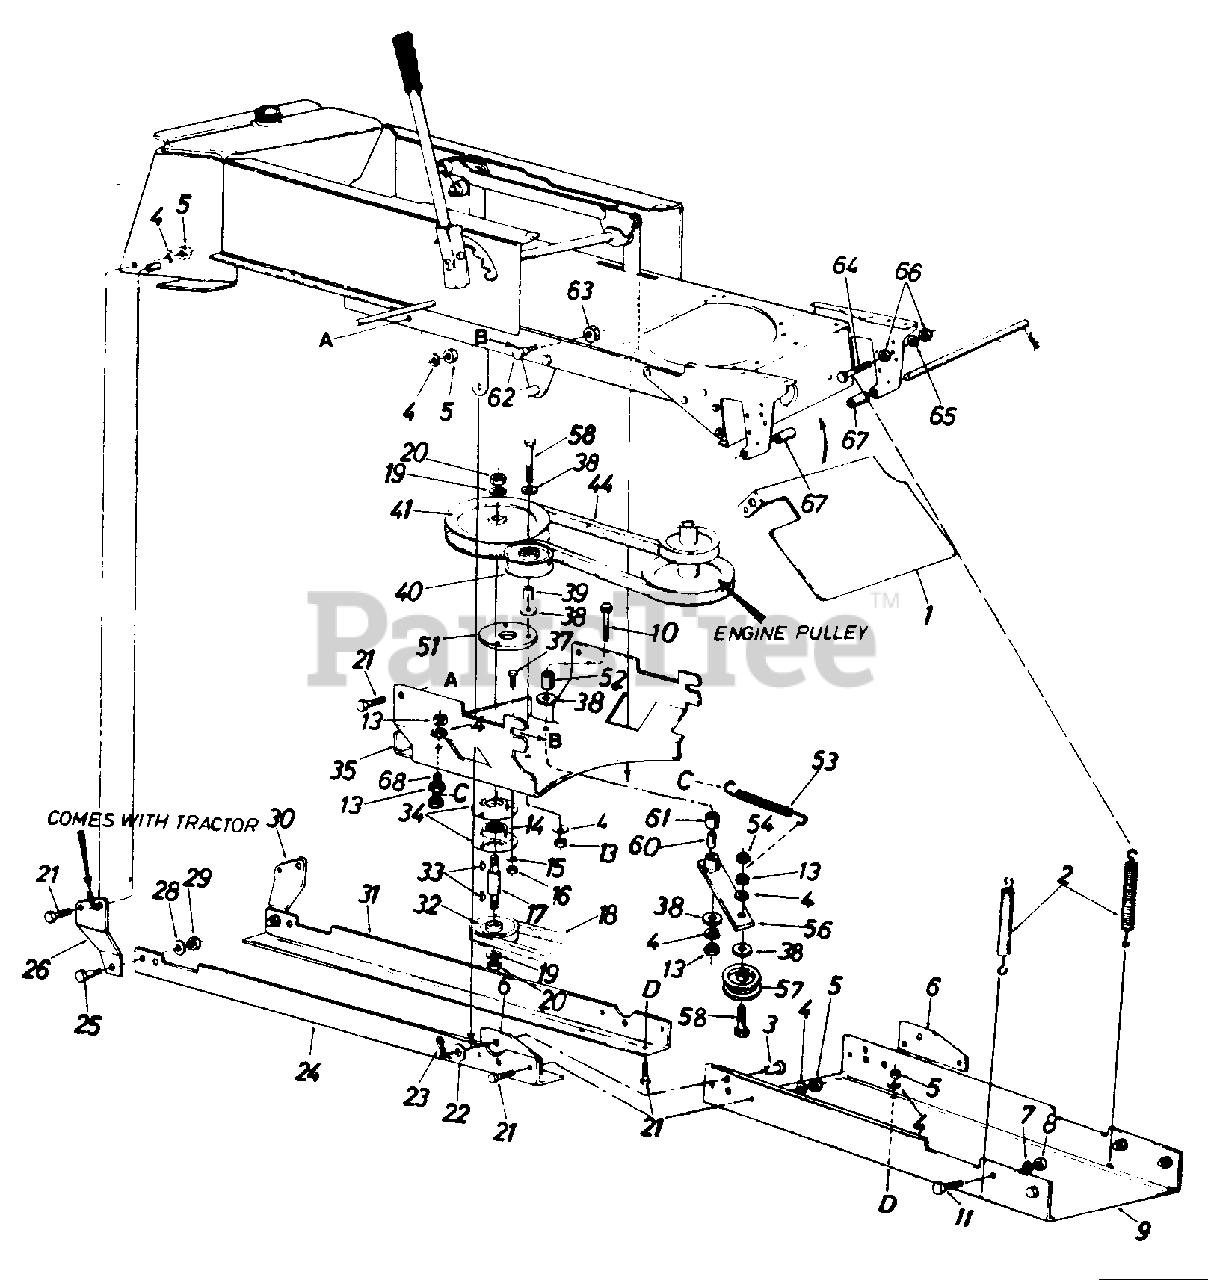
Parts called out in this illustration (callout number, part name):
3	Clevis Pin
4	L.-Wash. 3/8" I.D.
5	Hex L.-Nut 3/8-24 Thd.
6	Attaching Plate
7	L.-Wash. 1/2" I.D.
8	Hex L.-Nut 1/2-20 Thd.
11	Hex Bolt 1/2-20 x 1.25" Lg.
13	Hex Jam Nut 3/8-16 Thd.
14	Ball Bearin
15	L.-Wash. 5/16" I.D.
16	Hex Nut 5/16-18 Thd.
17	Spindle
18	"V"-8elt
19	L-Wash. 5/8" I.D.
20	Hex Jam Nut 5/8-11 Thd.
21	Hex Bolt 3/8-24 x 1.00" Lg.
22	Flat Washer
23	Internal Cotter Pin
29	Hex Nut 7/16-14 Thd.
33	#6 Hi-Pro Key 3/16 x 5/8" Dia.
34	Bearing Housing N
35	Supporting Bracket N
37	Hex Sems Bolt 5/16-18 x l"
38	Fl.-Wash. .38" I.D. x l" O.D.
39	Spacer .38" I.D. x .62' O.D.
40	Fl.-ldler Pulley
41	Upper Drive Pulley
44	"V"-Belt
53	Extension Spring 4.75" Lg.
54	Hex Cent. L.-Nut 3/8-16 Thd.
56	Idler Arrn Ass'y.
57	Idler Pulley
58	Hex Bolt 3/8-16 x 2.25" Lg.
60	Spacer .377" I.D. x .83" Lg.
61	Spacer .38" I.D. x .565" Lg.
62	Shoulder Bolt .498 Dia.
63	Hex Cent. L-Nut 3/8-16 Thd.
64	Hex Bolt 1/4-28 x 1.50" 4.
65	L.-Wash. 1/4" I.D.
66	Hex Nut 1/428 Thd.
67	Spacer .63" I.D. x 1.75" Lg.
68	Hex Bolt 3/8-16 x 2" Lg.
